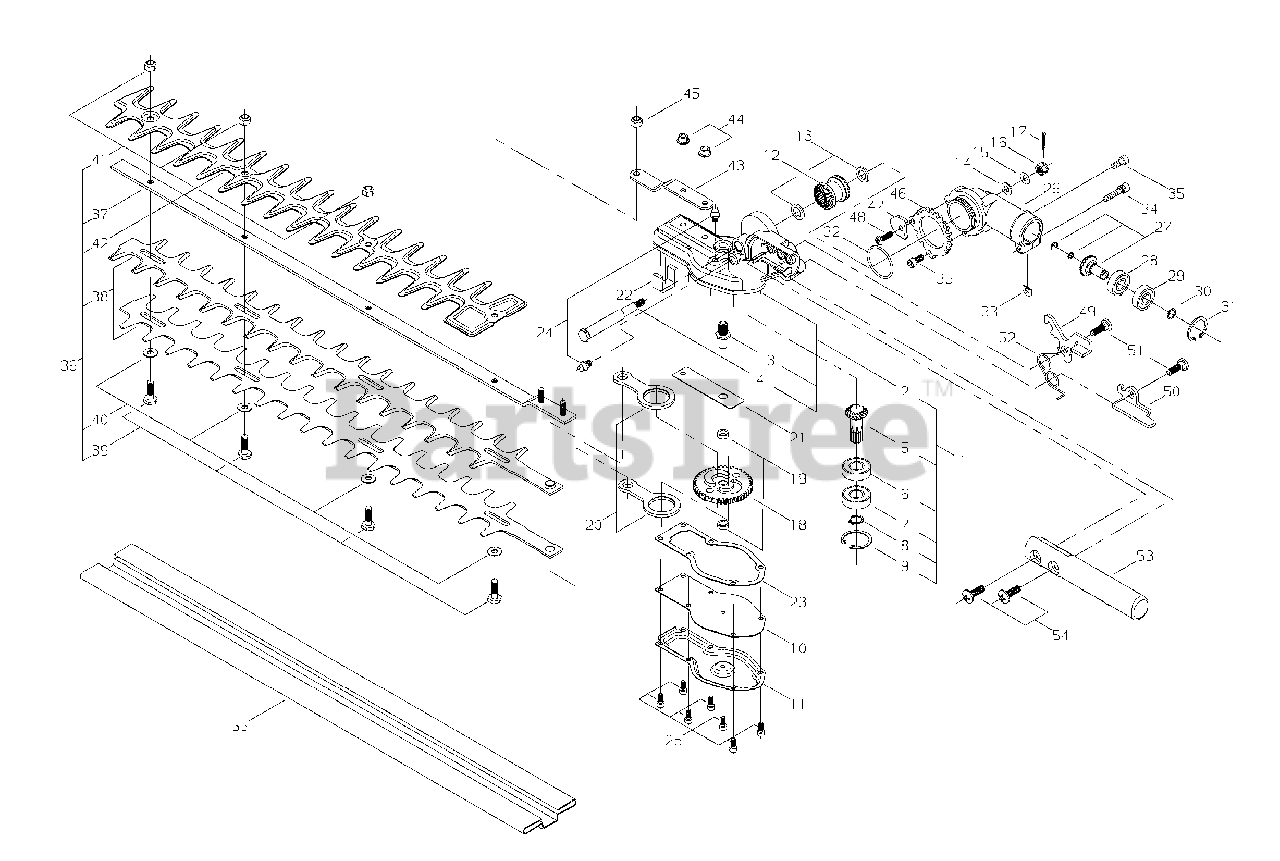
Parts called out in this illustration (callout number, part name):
1	GEAR CASE ASSY
2	CASE, GEAR - LOWER
3	PIPE, MAIN
4	SHAFT
5	GEAR - SHAFT
6	BEARING, BALL - 6001
7	BEARING, BALL - 6001ZZ
8	RING, RETAINING - 12
9	RING, RETAINING - 28
10	PLATE, GEAR CASE
11	CASE, GEAR - LOWER
12	GEAR SET - BEVEL
13	COLLAR
14	WASHER - 6
15	WASHER - CONICAL
16	NUT - CASTLE
17	PIN, SPLIT
18	CAM GEAR
19	SPACER
20	ROD, CONNECTING
21	PLATE, GUIDE
22	SEAL, FELT
23	GASKET
24	FITTING, GREASE
25	SCREW - 4X10
26	CASE, GEAR - UPPER
27	GEAR - BEVEL
28	BEARING, BALL - 609
29	BEARING, BALL - 609ZZ
30	RING, RETAINING
31	RING, RETAINING - 24
32	O-RING
33	SHIM
34	SCREW - 5X25
35	SCREW - 5X12
36	BLADE KIT - 22" (55cm)
37	GUIDE BAR - 22" (55cm)
38	BLADE KIT - 22" (55cm) CHROME
39	BOLT - 6X20
40	WASHER - 6
41	LOCKNUT - 6
42	GUARD, CUTTER BLADE
43	BRACKET, CUTTER
44	NUT - 5 -- FLANGE
45	LOCKNUT - 6
46	PLATE, ADJUST
47	STOPPER PLATE
48	SCREW - 5X16
49	LEVER, LOCK
50	LEVER, LOCK
51	SCREW
52	SPRING
53	LEVER, ADJUSTMENT
54	SCREW - 6X20
55	COVER, BLADE
